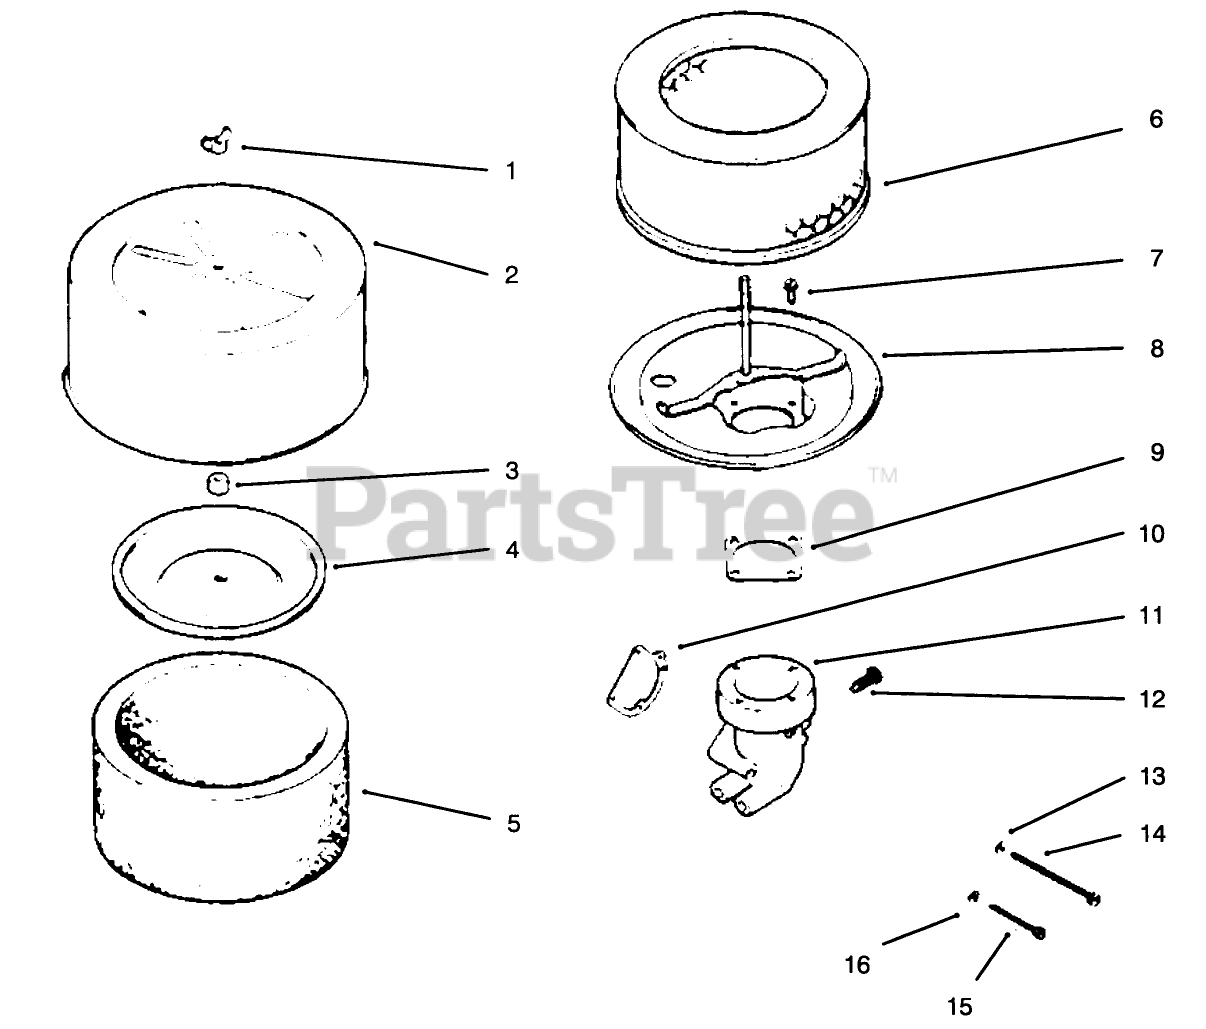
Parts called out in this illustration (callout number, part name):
1	Nut-Wing
2	Cover-Air Cleaner
3	Seal
4	Cover-Element
5	Precleaner
6	Element
7	Screw-H.C.
8	Base-Air Cleaner
9	Gasket-Air Cleaner
10	Gasket-Elbow
11	Elbow-Kit (Incl. Ref. #10 & 12)
12	Screw-Self Tap
13	Washer
14	Screw-R.H.M.
15	Screw-R.H.M.
16	Washer
